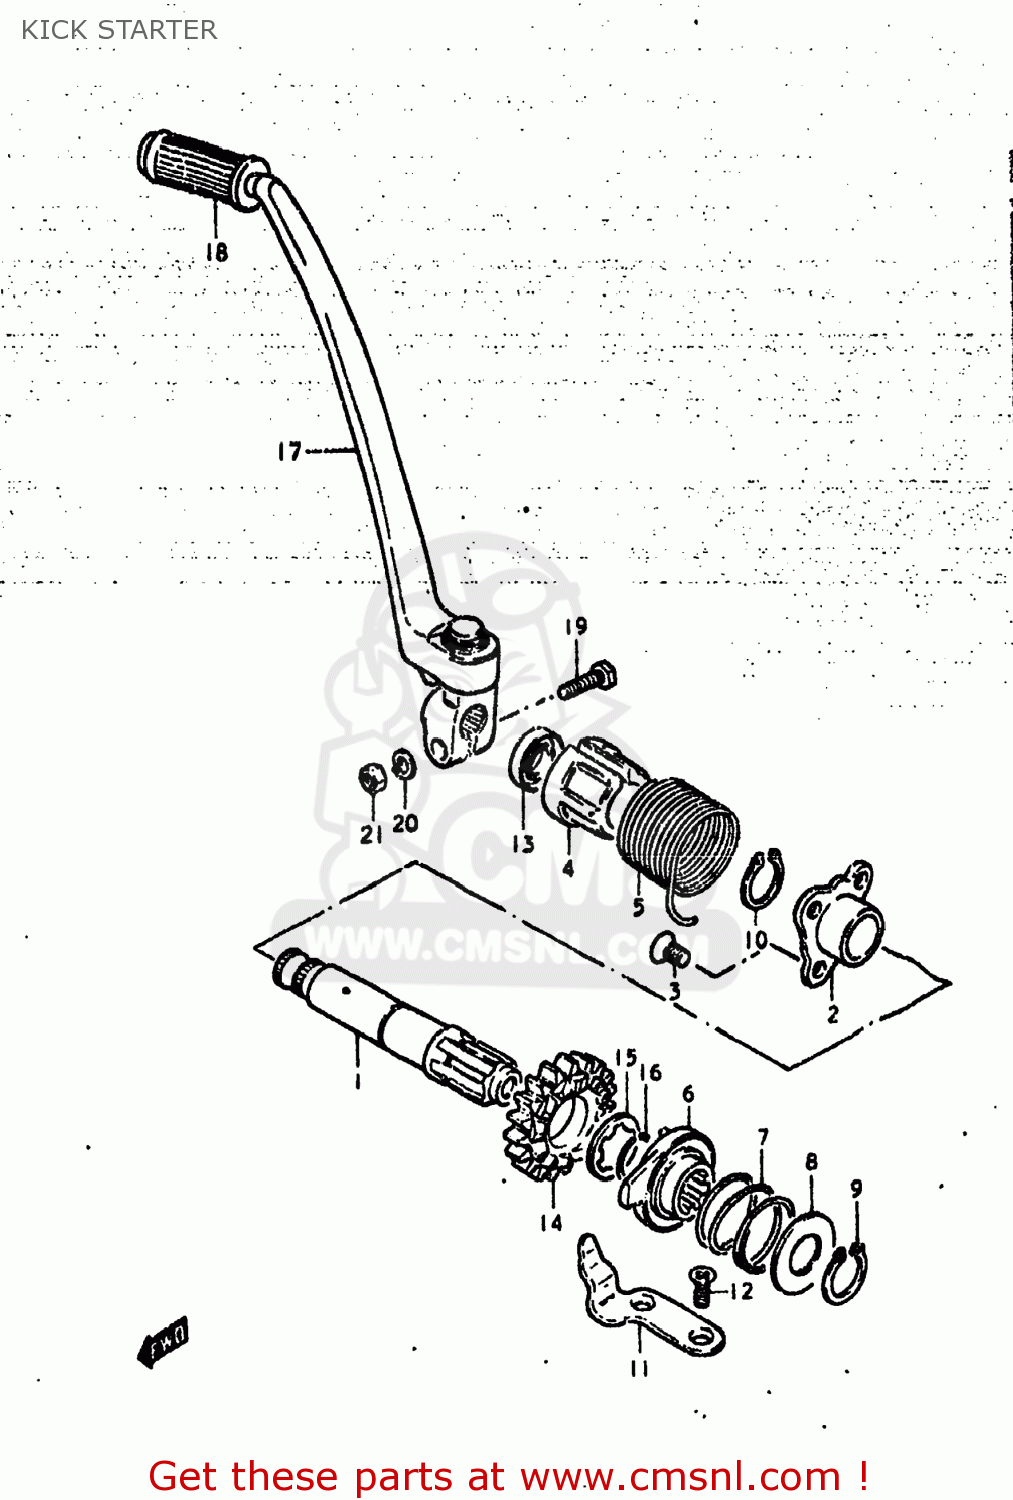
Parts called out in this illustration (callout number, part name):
1	SHAFT,KICK STARTER
2	HOLDER,KICK STARTER SHAFT
3	SCREW
4	GUIDE,STARTER SHAFT SPRING
5	SPRING
6	STARTER,KICK
7	SPRING
8	WASHER
9	CIRCLIP
10	CIRCLIP
11	GUIDE,STARTING SPRING
12	SCREW
13	SEAL,OIL(20X27X5)
14	GEAR,KICK STARTER DRIVE
15	WASHER,LOCK
16	CIRCLIP
17	LEVER ASSY,KICK STARTER
18	RUBBER,KICK STARTER PEDAL
19	BOLT,M10X1.25X
20	LOCK WASHER
21	NUT
